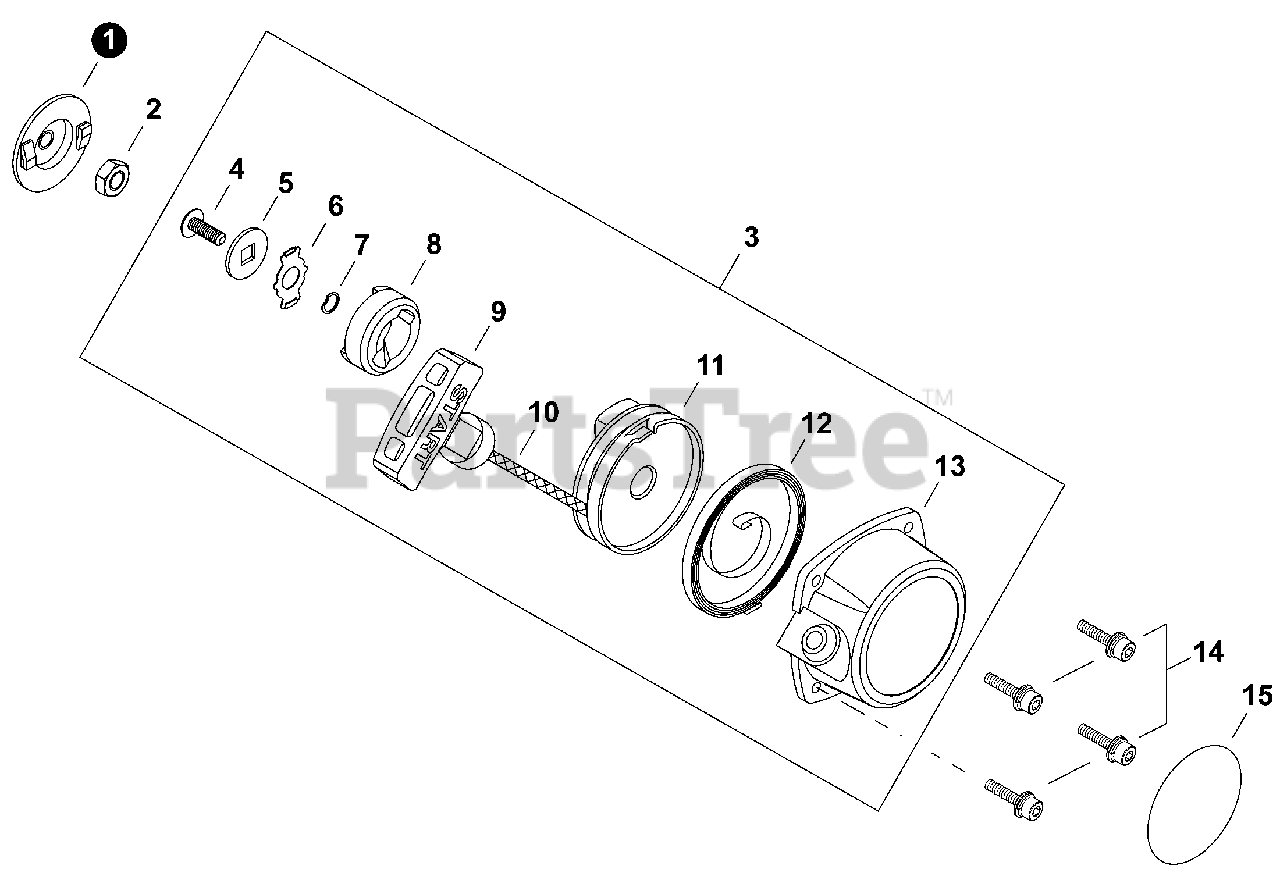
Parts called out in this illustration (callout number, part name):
1	PULLEY, STARTER
2	NUT M8×1
3	STARTER ASSY, RECOIL
4	SCREW 5 MM
5	WASHER 5 MM
6	RETAINER
7	WASHER, WAVE
8	RATCHET
9	GRIP, STARTER
10	ROPE, STARTER
11	REEL, ROPE
12	SPRING, RECOIL
13	CASE, RECOIL STARTER
14	BOLT, ADHESIVE M4×16
15	LABEL, SHINDAIWA PROFESSIONAL
